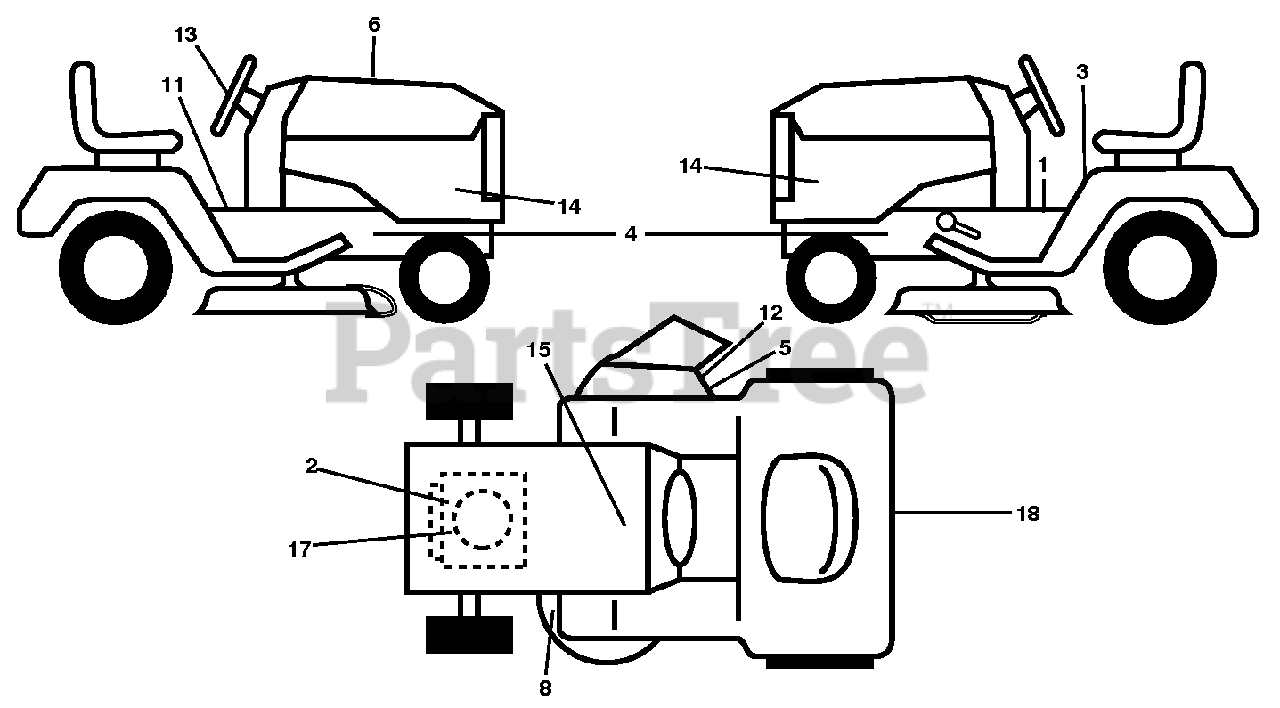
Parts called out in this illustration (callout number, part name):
6	DECAL.RPL.BSM44.PROF.TGW.42E.K
14	Decal, Side Panel LT2742A2 BR 13 Jonsered
15	DECAL BTRY SYMBOLS
